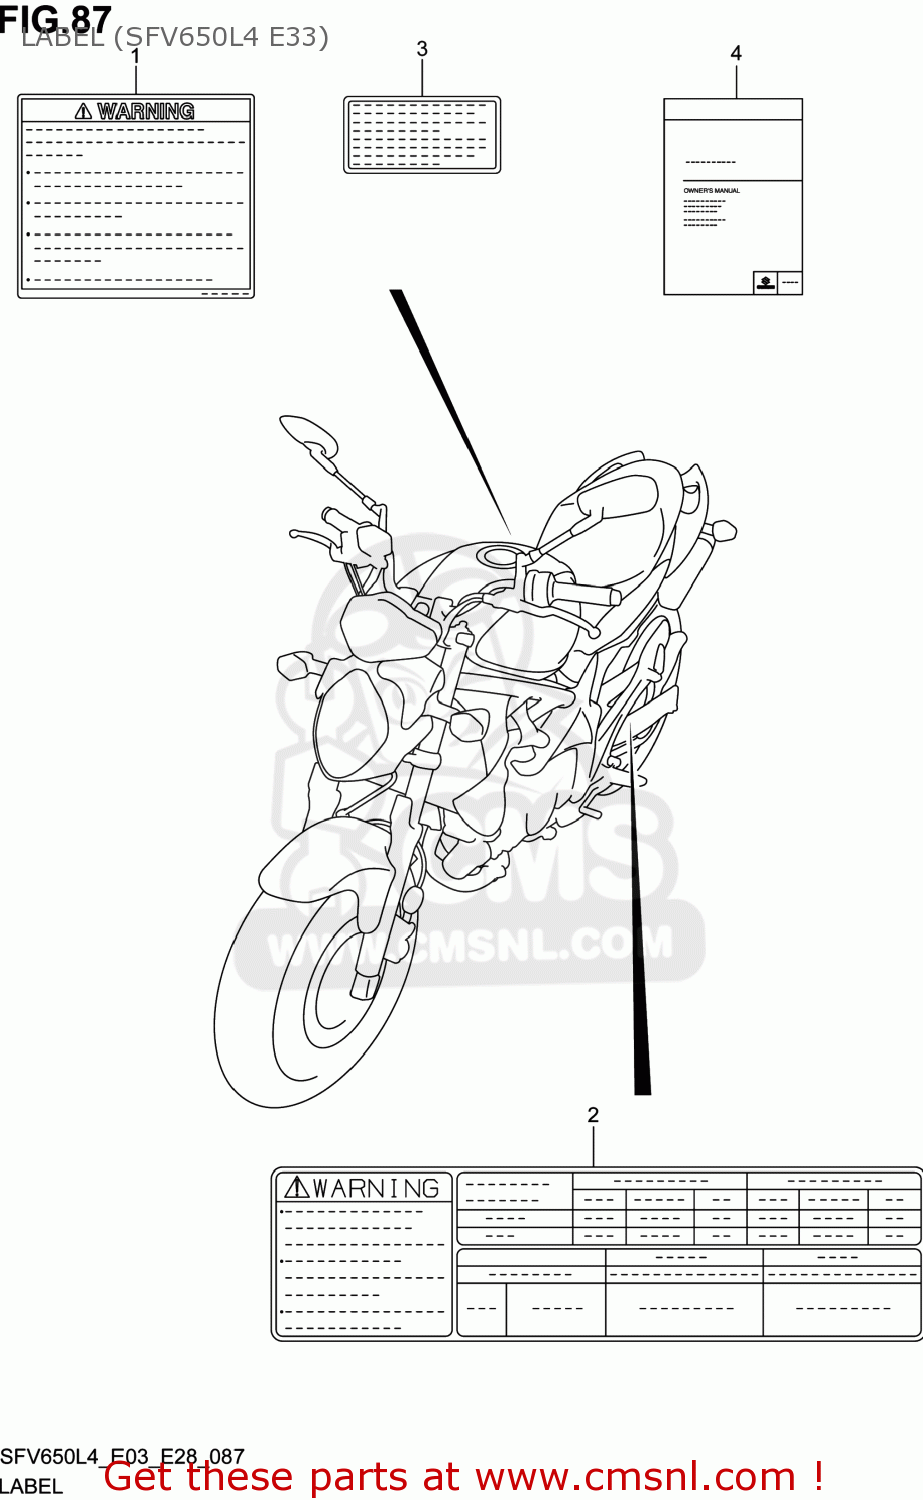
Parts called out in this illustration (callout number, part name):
1	LABEL,GENERAL WARNING
2	LABEL,TIRE INFORMATION
3	LABEL,MANUAL NOTICE
4	MANUAL,OWNER'S
